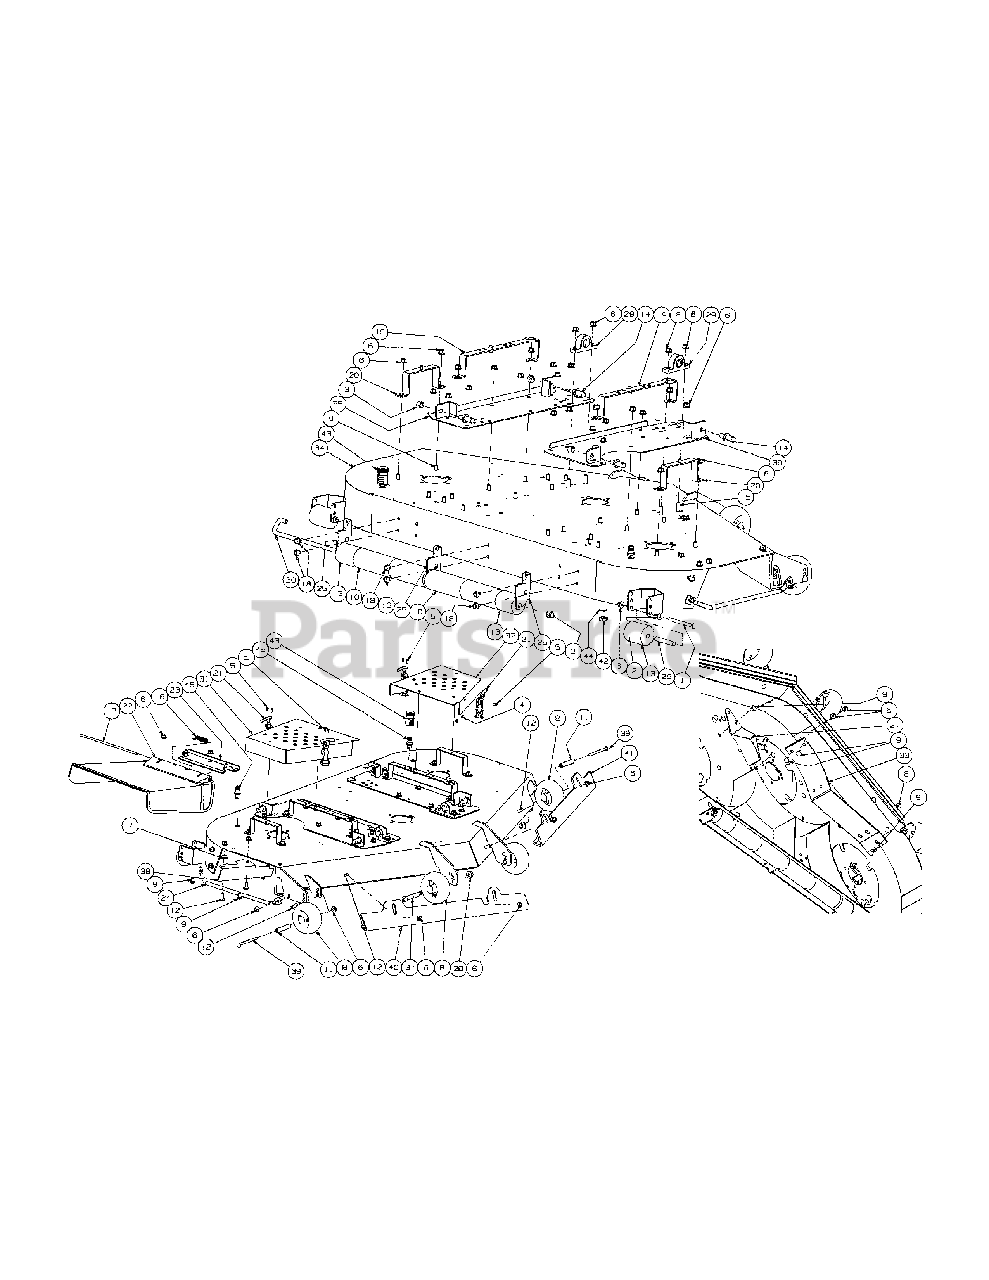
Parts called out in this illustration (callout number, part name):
1	Hex Cap Screw, 3/8-16, 3.75
2	Flat Washer, 3/8
3	Lock Nut, Nylon Insert, 1/2-13
4	Lock Nut, Nylon Insert, 10-32
5	Phillips Head Screw, 10-32
6	Flange Lock Hex Nut, 3/8-16
7	Idler Washer
8	Complete Wheel, 5.00 Dia.
9	Carriage Bolt, 3/8-16 x .75 Lg.
10	Front Roller
11	Wheel Spacer
12	Carriage Bolt, 3/8-16 x 1
13	Grass Catcher Roller
14	Pin, 5/8 Dia. x 1.2 Lg.
15	Carriage Screw, 3/8-16 x 1.25
16	Torsion Spring, 0.4ID x 2.16Lg
17	Chute Deflector Rod
18	Hex Index Washer Screw, 3/8-16, .5
19	Belt Cover Support
20	Outer Belt Cover Support Assembly
21	T-Handle Latch Draw
22	Chute Deflector
23	Chute Deflector Bracket
24	Finger Guard
26	Spacer, .385 x .50 x 3.045
27	Discharge Baffle
28	Nut, 1/2-13, FlangeLock
29	Pillow Block
30	J-Hook w/ Threaded Roller
31	Right Hand Deck Belt Cover
32	Left Hand Deck Belt Cover
33	Baffle, 60" Adjustment
34	60" Deck Assembly
35	Left Hand Deck Weldment Mounting Plate
36	Right Hand Deck Weldment Mounting Plate
37	Shoulder Bolt, .625 x 3.00 x 3/8-16
39	Carriage Bolt, 3/8-16 x 4.00
40	Right Hand Front Adjustment Skirt
41	Left Hand Front Adjustment Skirt
42	Hex Nut, M16-1.5
43	Water Nozzle Adaptor
44	Lock Washer, 17 x 23.8 x 1.95
45	Deck Water Nozzle
